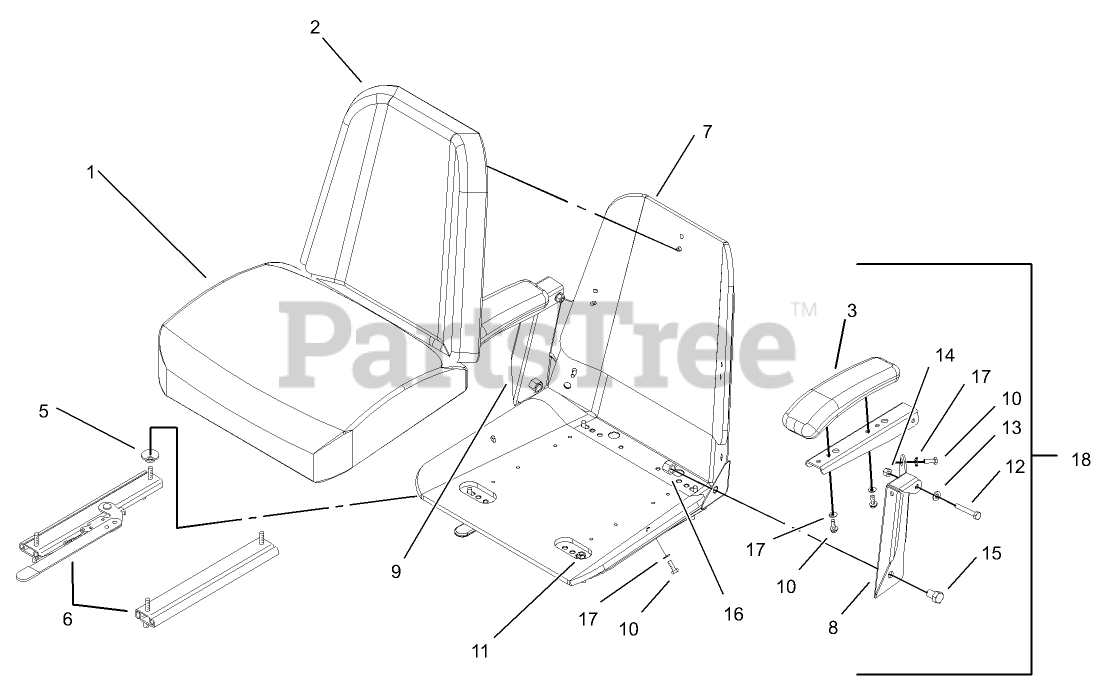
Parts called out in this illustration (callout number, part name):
1	CUSHION,SEAT BOTTOM
2	CUSHION-SEAT, BACK
3	CUSHION-ARMREST
5	SPACER-TRACK
6	TRACK-SEAT
7	FRAME-SEAT
8	Bracket-Armrest, LH
9	Bracket-Armrest, RH
10	SCREW-HH
11	NUT-HF
12	SCREW-HH
13	WASHER-PLAIN
14	NUT-LOCK, NI
15	SCREW-HH
16	NUT-LOCK, NI
17	WASHER-FLAT
18	ARMREST KIT
